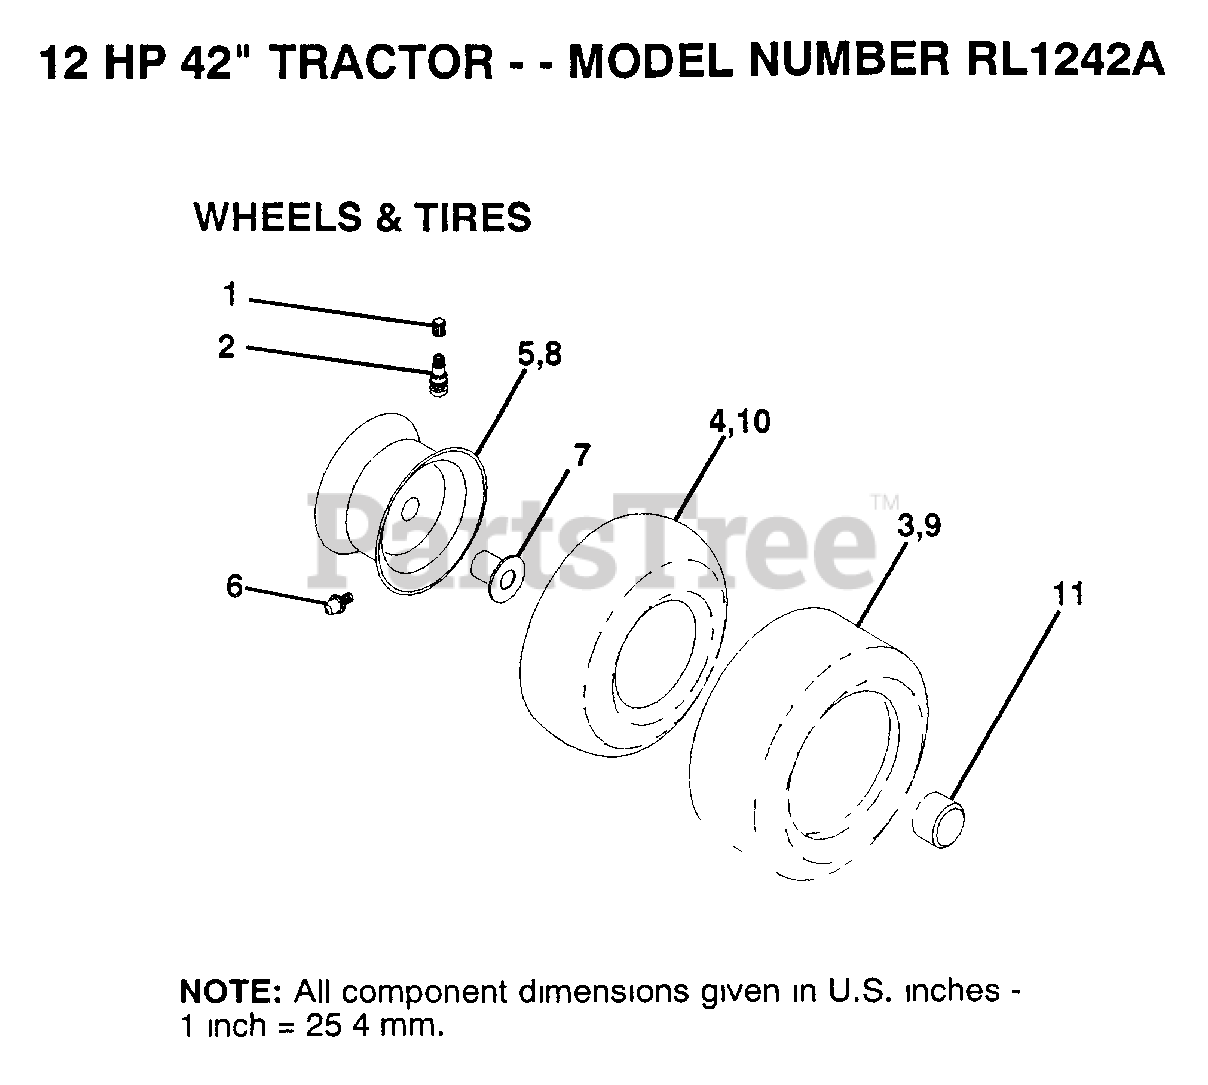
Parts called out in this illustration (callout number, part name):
1	VALVE CAP
2	VALVE STEM LT
4	TUBE.5.3/4.5/6
6	FITTING LT
7	"FLANGE, BEARING"
10	TUBE.18X9.5-8
11	HUB CAP
